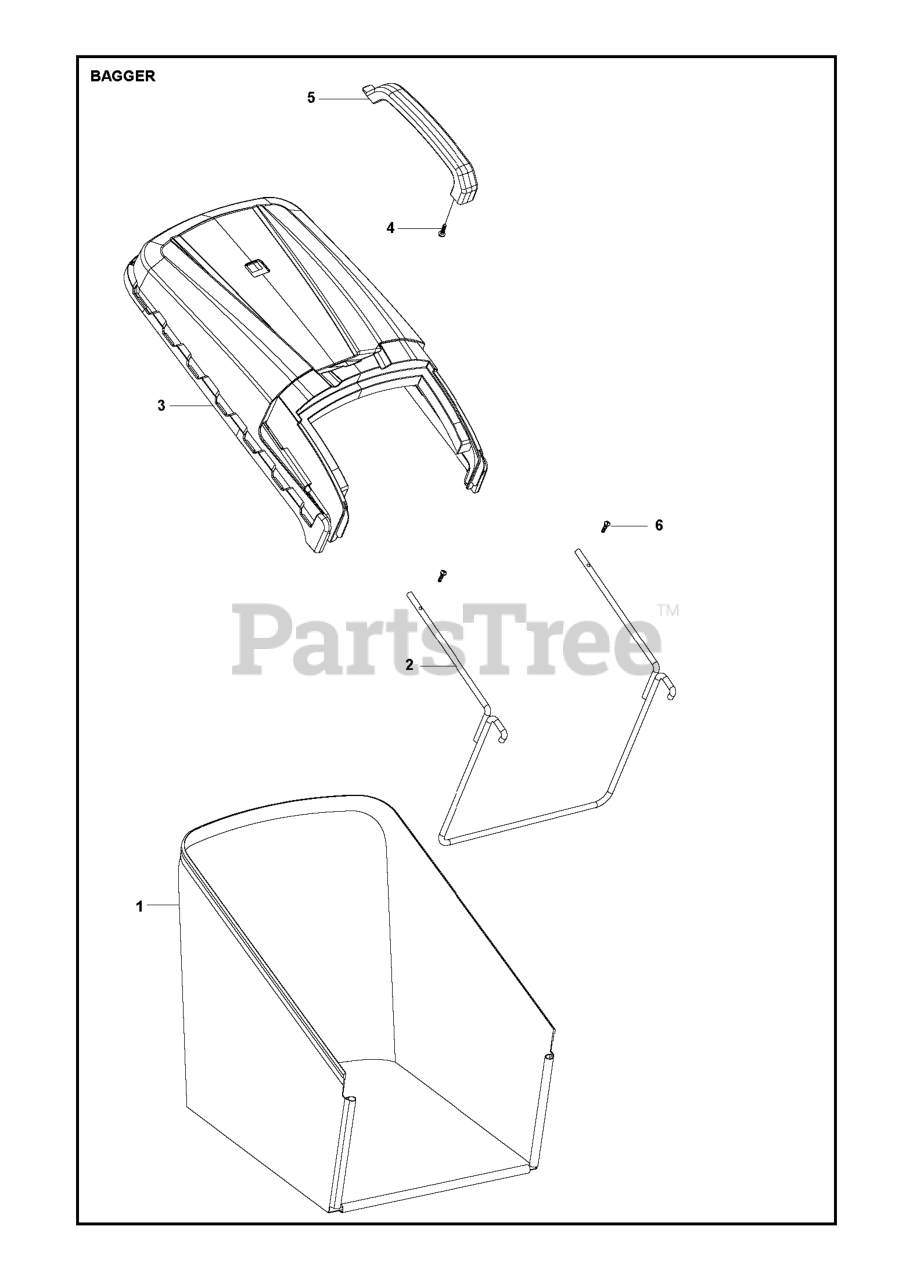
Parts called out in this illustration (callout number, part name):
1	GRASSBAG #25100173001
2	BRACKET #26300299201
3	COVER GRASS CATCHER #253417001
4	SCREW ST4.8*19,GB845 #26800104
5	HANDLE #25341800101
